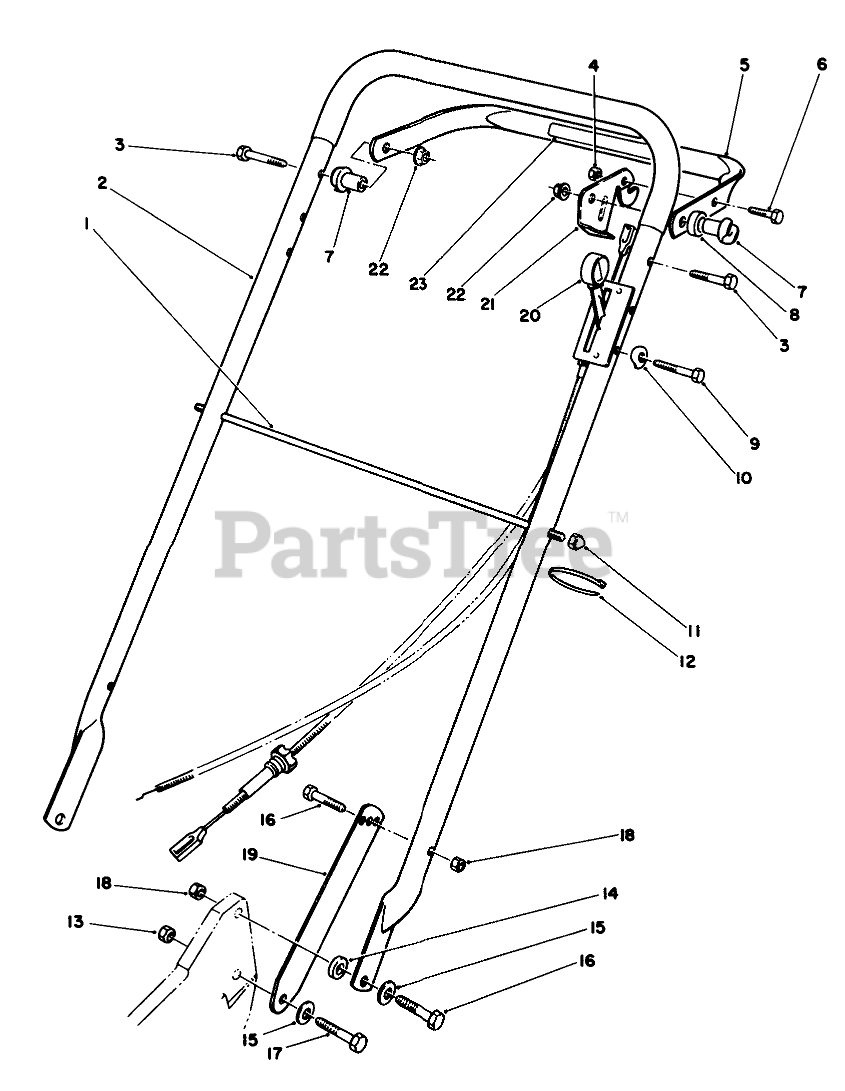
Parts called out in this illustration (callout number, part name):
1	ROD-SUPPORT, BAG
2	Handle
3	SCREW-HH
4	NUT-LOCK, NI
5	Bar-Control
6	SCREW-HH
7	SPACER-SUPPORT
8	SPACER-NYLON
9	SCREW-HH
10	WASHER
11	NUT-CAP
12	TIE-CABLE
13	NUT-LOCK, NI
14	SPACER-PIN, MOUNTING
15	WASHER-BELLEVILLE
16	SCREW-HH
17	SCREW-HH
18	NUT-LOCK, NI
19	HANDLE LATCH
20	Throttle Control Assembly (Model No. 22700C Only)
21	LEVER-CONTROL
22	NUT-HF
23	DECAL - INT'L TRACTION
